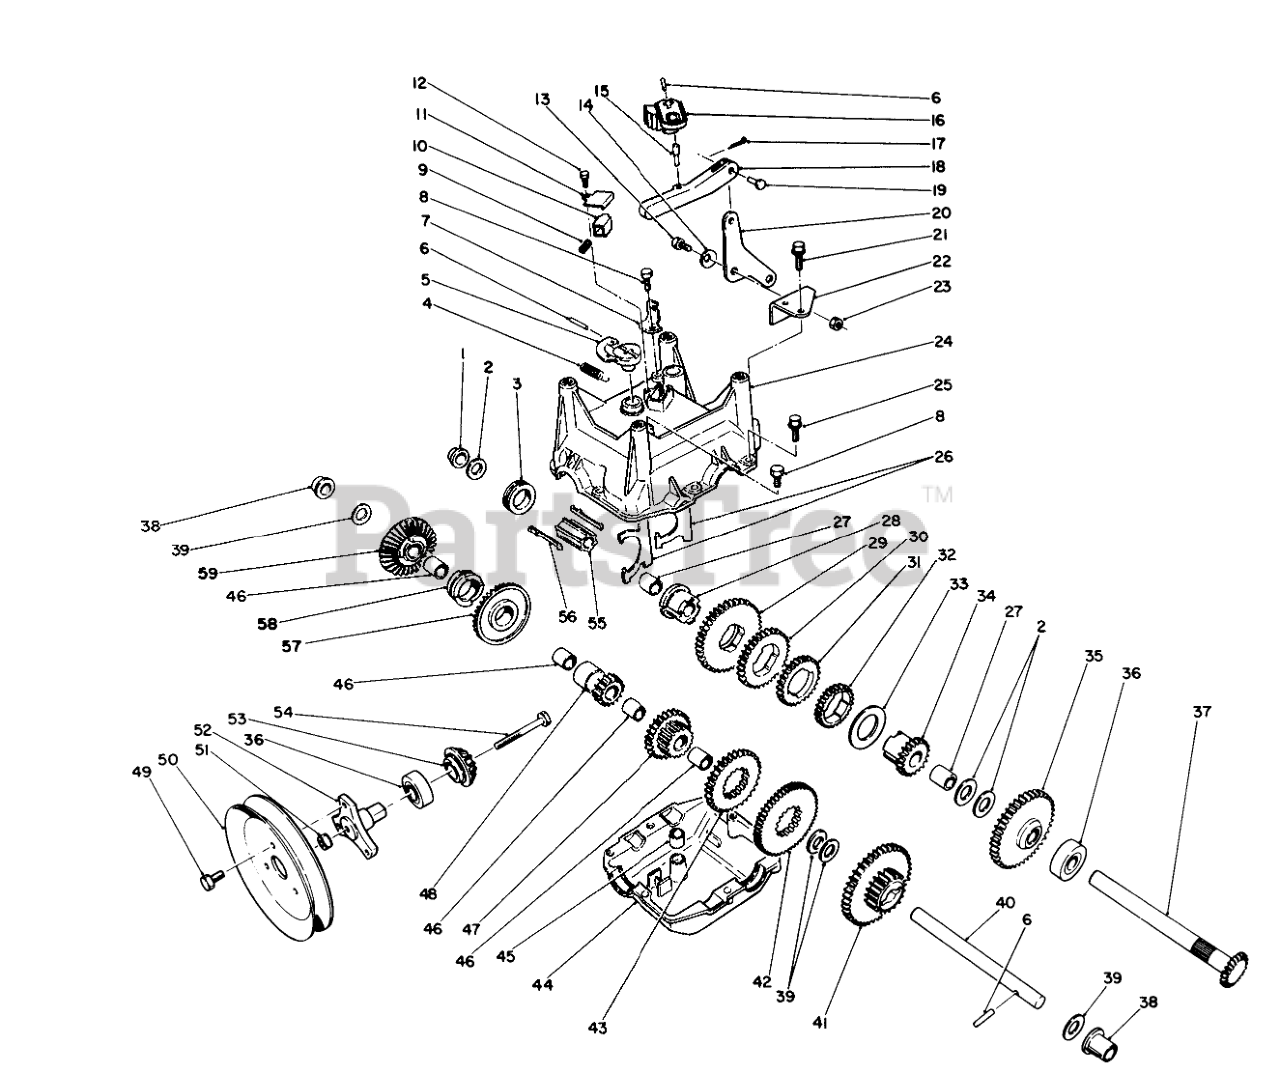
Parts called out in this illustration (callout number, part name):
1	BUSHING-FLANGE, OUTPUT
2	BEARING-THRUST
3	COLLAR-SHIFT
4	SPRING-EXTENSION
5	LEVER
6	PIN-SPRING
7	BRACKET-CABLE
8	SCREW-HWH
9	SPRING-DETENT
10	BUTTON-DETENT
11	COVER-DETENT
12	SCREW-HWH
13	SCREW-SHOULDER
14	WASHER-CURVED
15	PIN-LINK, GEAR SHIFT
16	LEVER-SHIFT, GEAR
17	PIN-COTTER
18	LINK-SHIFT, GEAR
19	PIN-CLEVIS
20	BELLCRANK
21	SCREW-HWH
22	BRACKET-BELLCRANK
23	NUT-LOCK, NI
24	GEARCASE-UPPER, CASING
25	SCREW-HWHTF
26	YOKE-SHIFT
27	BUSHING-OUTPUT
28	SLEEVE-GEAR
29	GEAR-45 T
30	GEAR-34 T
31	GEAR-27 T
32	GEAR-29 T
33	WASHER-THRUST
34	GEAR-SLEEVE, 19 T
35	GEAR-41 T
36	BEARING-BALL
37	SHAFT-OUTPUT
38	BUSHING-INTERMEDIATE
39	WASHER-THRUST
40	SHAFT-INTERMEDIATE
41	GEAR-19/41 T
42	GEAR-51 T
43	GEAR-33 T
44	GEARCASE-LOWER, CASING
45	BUSHING-YOKE
46	Bushing-Output
47	GEAR-26 T
48	GEAR-BEVEL, 15 T
49	SCREW
50	TRACTION-SHEAVE, HALF
51	NUT-HHF
52	HUB-PULLEY
53	PINION-BEVEL
54	SCREW-HH
55	SLEEVE-SHIFT
56	KEY-SHIFT
57	GEAR-BEVEL, 36 T
58	COLLAR-SHIFT
59	Gear-Bevel Reverse 36T (Incl. Ref. #46)
